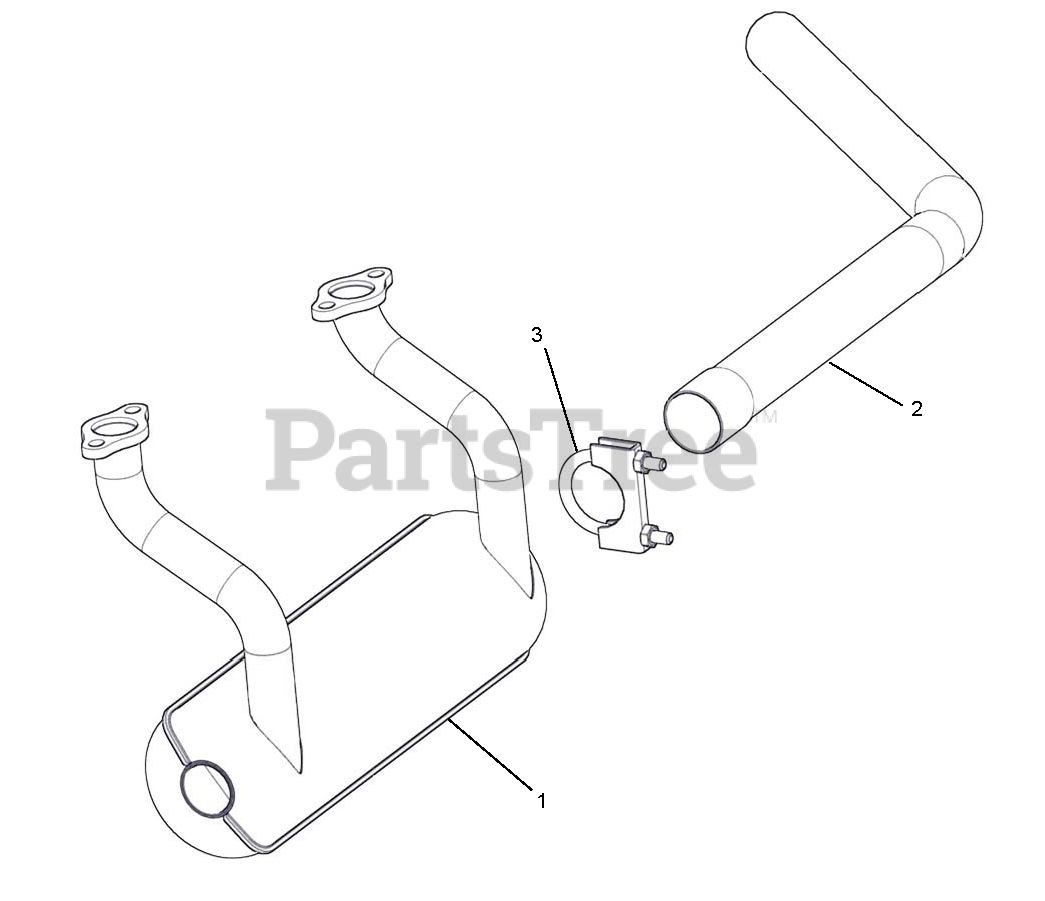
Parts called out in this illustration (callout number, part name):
1	MUFFLER, EH65
2	TAILPIPE, EH65
3	MUFFLER CLAMP, TREKER
